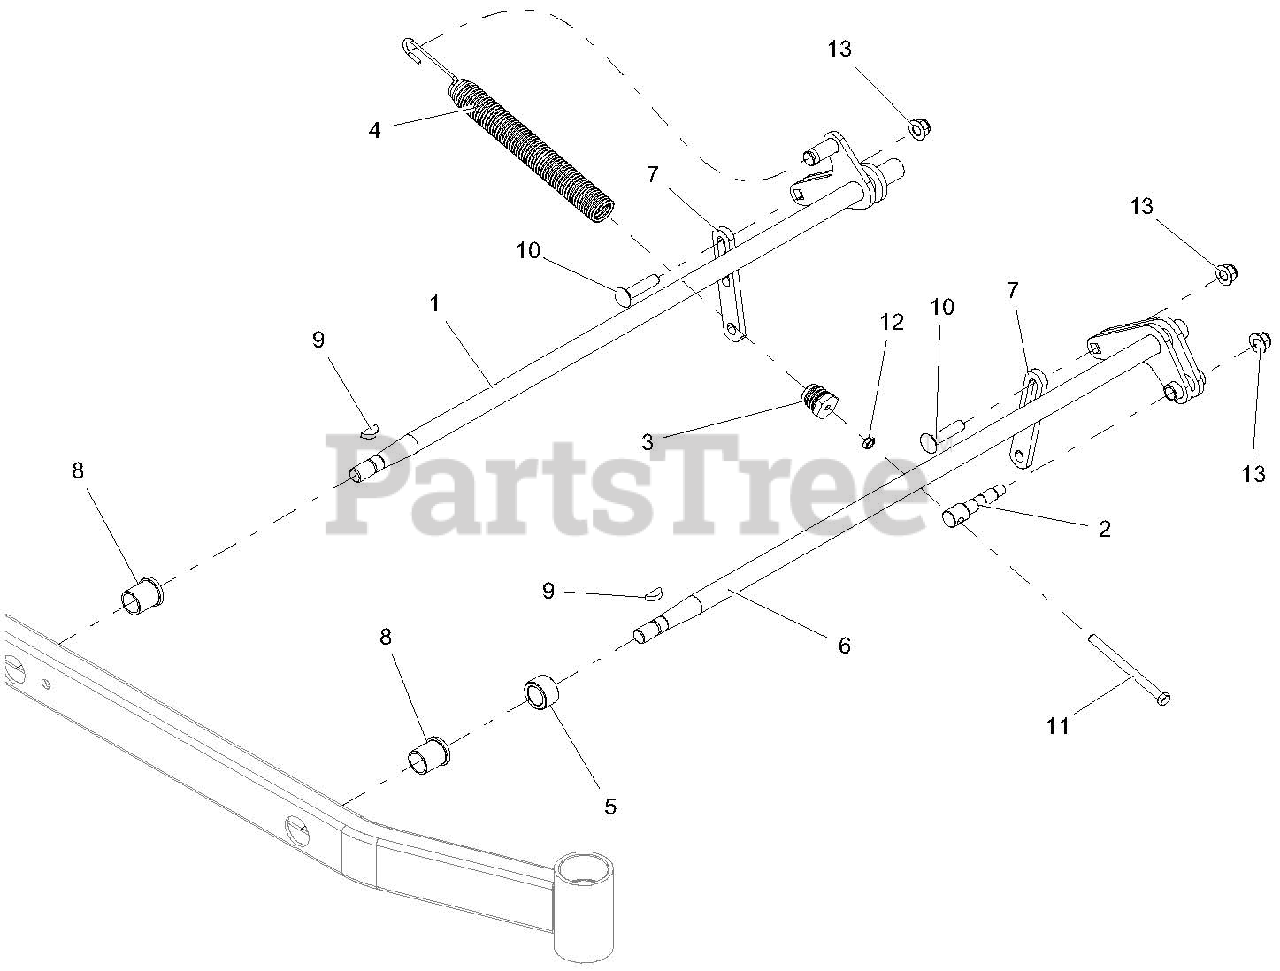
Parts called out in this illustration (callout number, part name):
1	WLDMT, REAR LH DECK LIFT ARM-BLACK
2	TRUNION, SPRG
3	PLUG, SPRG
4	SPRG, DECK LIFT
5	SPACER, 1.500 X 1.000 X .880
6	WLDMT, FRONT LH DECK LIFT ARM-BLACK
7	LINK, DECK LIFT - LONG
8	BSHG-FLG 1.00X1.25X1.5X1.5
9	KEY, WDRF .25 X 1.00 HRD #15
10	BLT-RDHDSQNK .50-13X2.25 G5 Y
11	BLT-HEX .38-16X5.00 GR5 YWZC
12	NUT, JAM .375-16 YWZC
13	NUT-LK-NYL-FLG .50-13 YWZC
